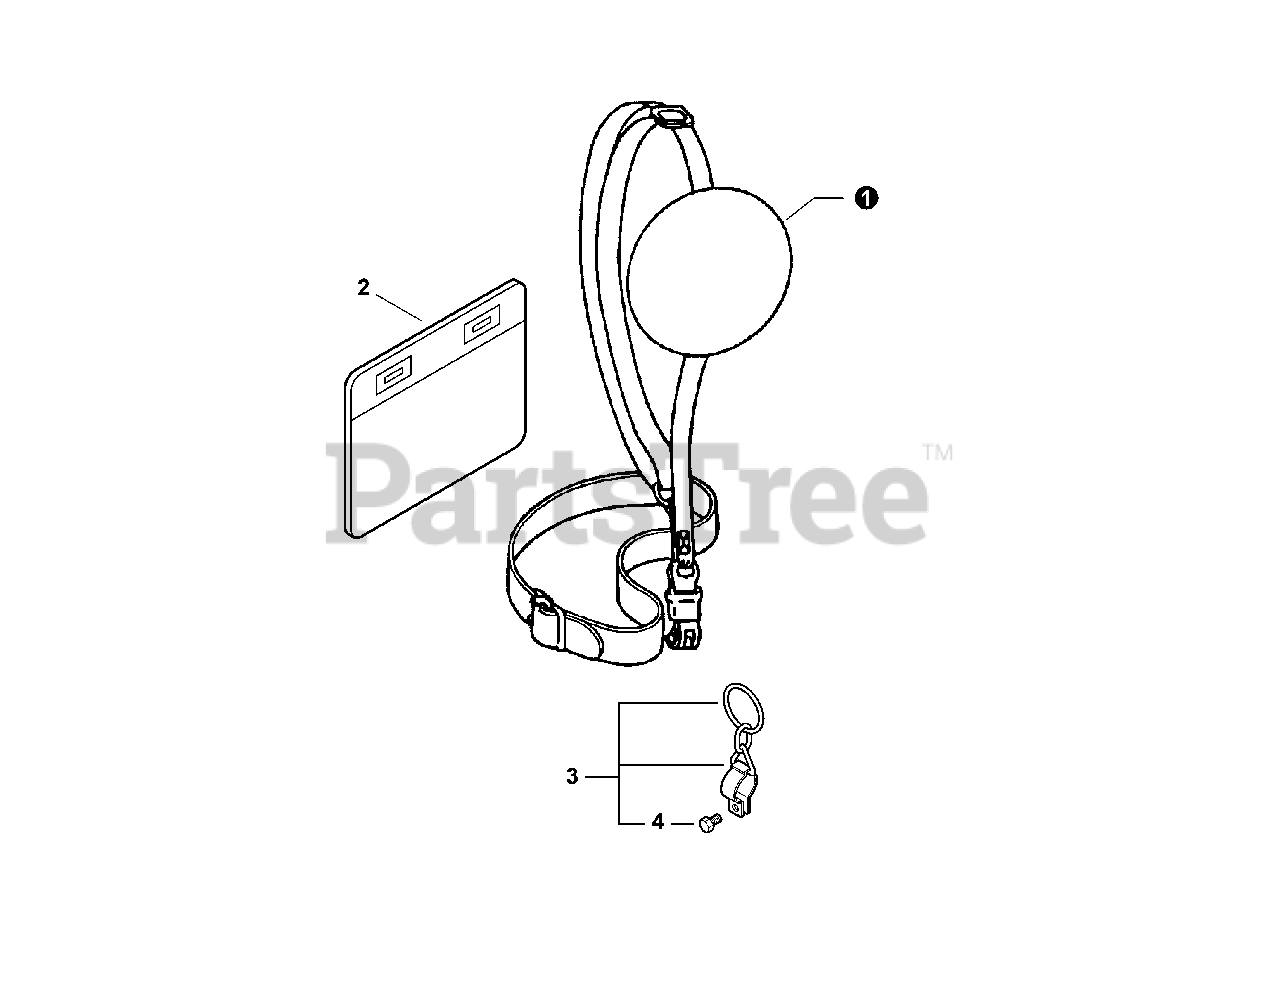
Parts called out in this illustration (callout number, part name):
1	HARNESS, SHOULDER
2	CUSHION
3	HARNESS HANGER KIT
4	BOLT, TORX - 5×12
